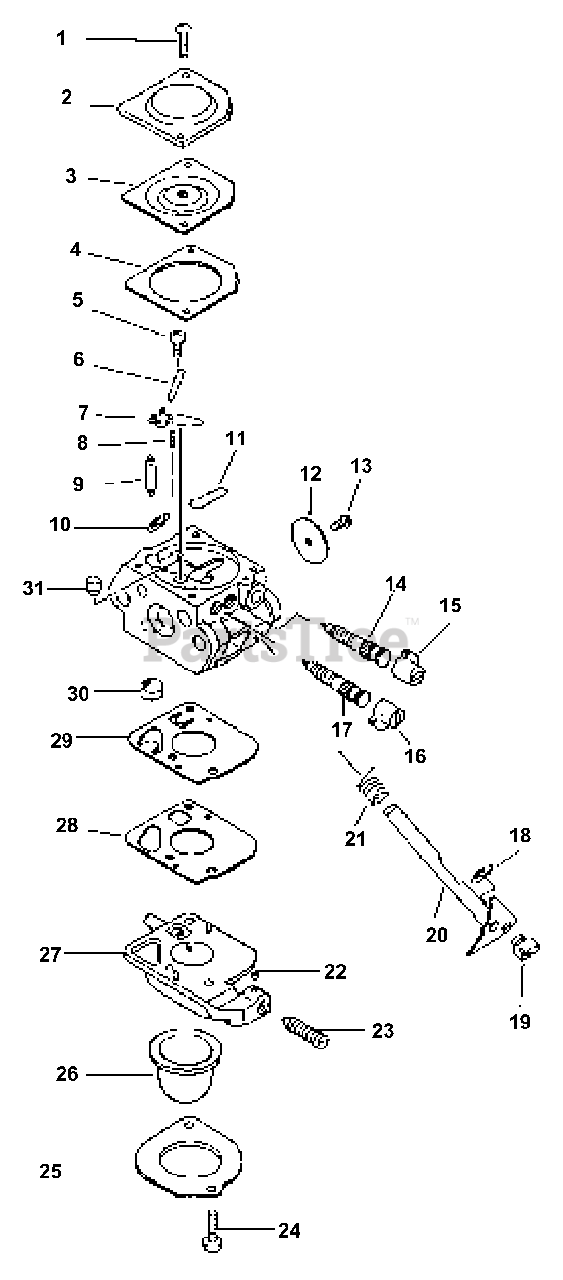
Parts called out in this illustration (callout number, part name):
2	COVER, METERING
3	DIAPHRAGM, METERING
4	GASKET, METERING
5	SCREW, METERING LEVER PIN
6	PIN, METERING LEVER
7	LEVER, METERING
8	SPRING, METERING LEVER
9	VALVE, INLET NEEDLE
10	RING, RETAINING
11	PLUG, WELCH
12	VALVE, THROTTLE
14	NEEDLE - LOW SPEED
15	CAP, LIMITER
16	CAP, LIMITER
17	NEEDLE - HIGH SPEED
18	RING, RETAINING
20	SHAFT, THROTTLE
21	SPRING, RETURN
22	PIECE, FRICTION
23	SCREW, IDLE ADJUST
24	SCREW, RETAINER
25	RETAINER, PURGE BULB
26	BULB, PURGE
27	BASE, PURGE
28	GASKET, PUMP
29	DIAPHRAGM, PUMP
30	STRAINER
31	NOZZLE, CHECK VALVE
